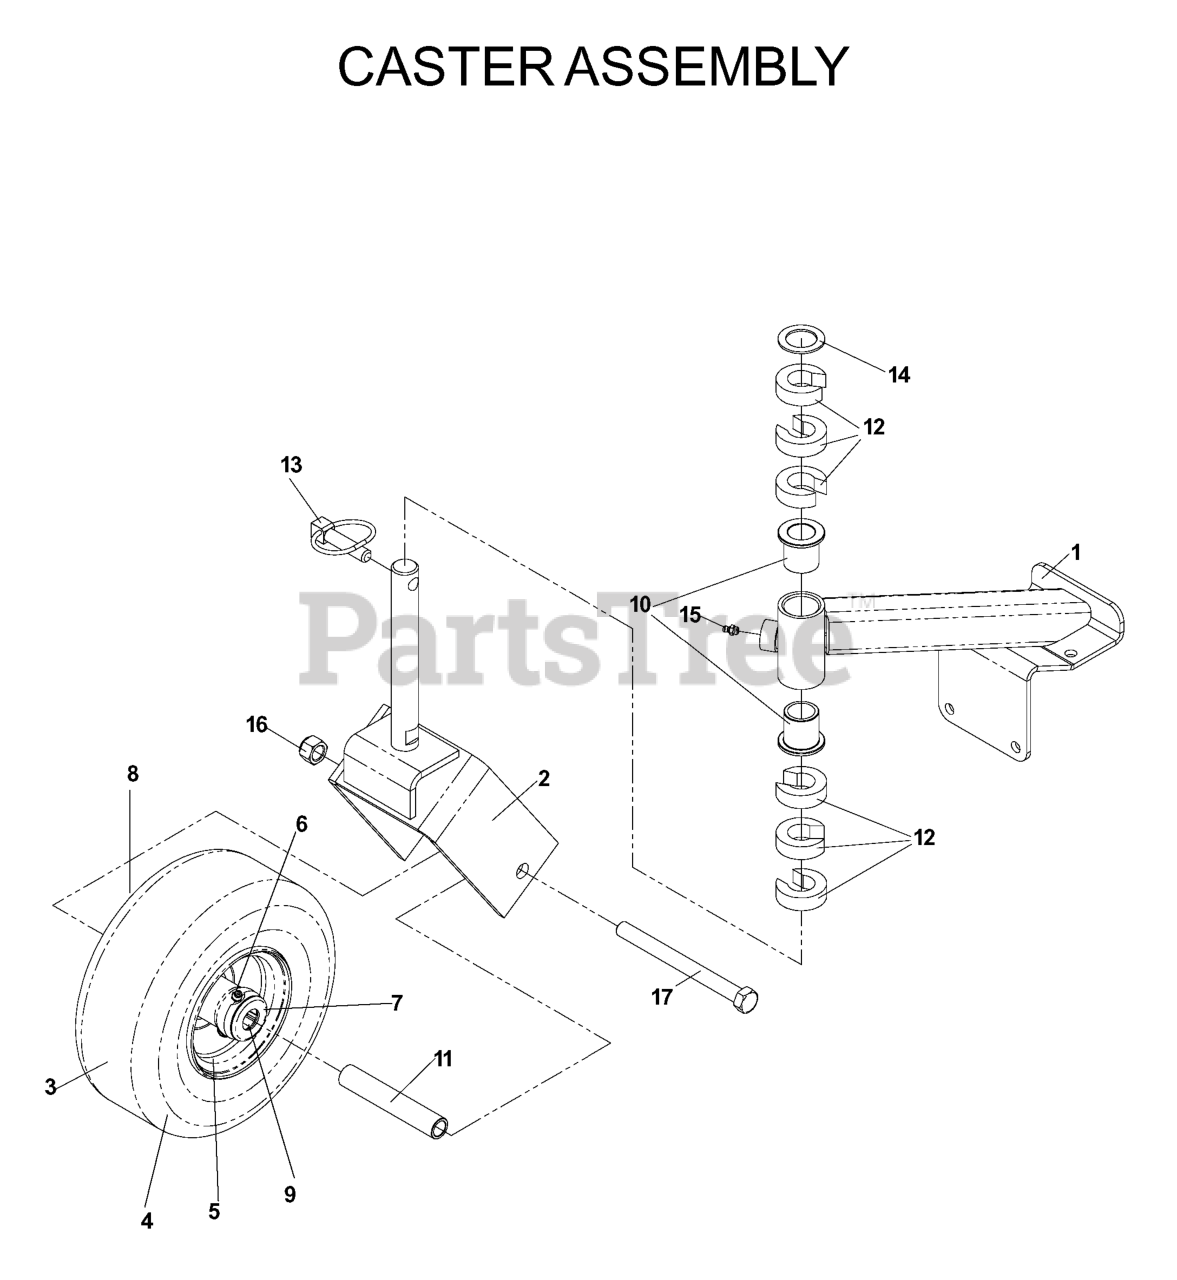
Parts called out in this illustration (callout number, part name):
1	CASTER ARM W/ BUSHING
2	CASTER FORK, ORANGE
3	TIRE/WHEEL.CASTER.9X3.5-4.SMOO
4	TIRE 9 X 3.5 - 4
6	GREASE ZERK
7	ENDCAP
8	ENDCAP, NOTCHED
9	ROLLER BEARING
10	BUSHING, FLANGED
13	LYNCH PIN 7/16
14	MACHINE BUSHING
15	ZERK
16	NUT 1/2-13 HEX NYLOC ZD
17	HCS 1/2C X 5 1/2
539912234	VALVE STEM TR-412
